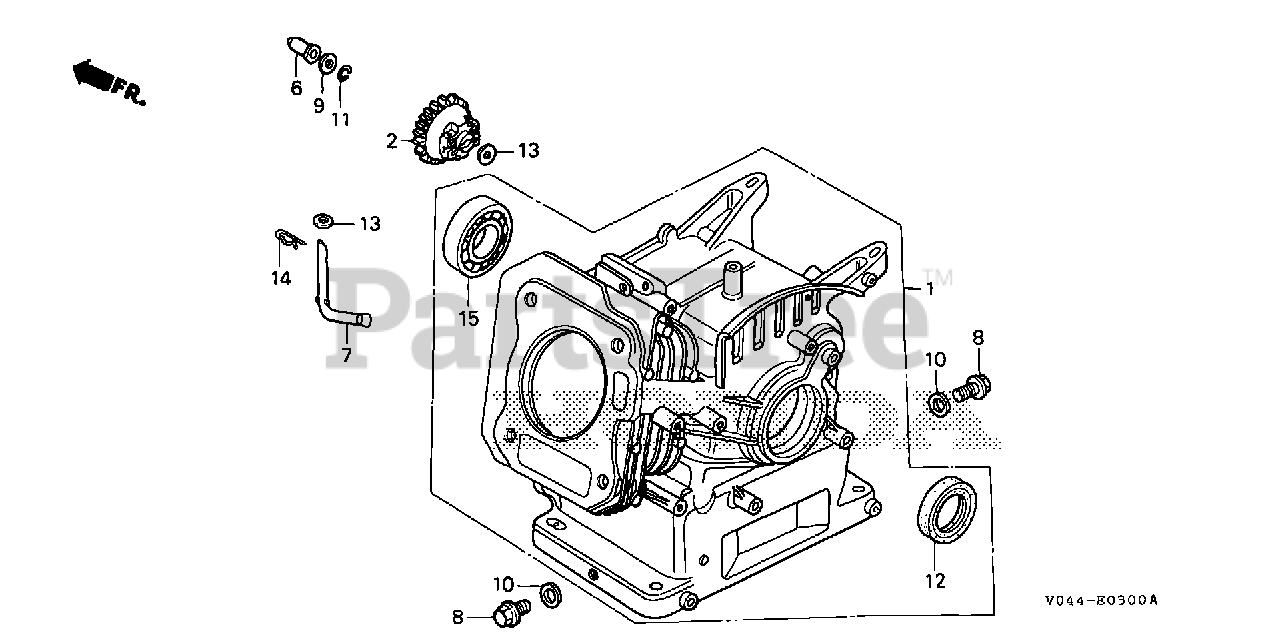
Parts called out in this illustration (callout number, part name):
1	CYLINDER ASSY.
2	GOVERNOR ASSY.
6	SLIDER, GOVERNOR
7	SHAFT, GOVERNOR ARM
8	BOLT, DRAIN PLUG
9	WASHER, THRUST (6MM)
10	WASHER, DRAIN PLUG (10.2MM)
11	CLIP, GOVERNOR HOLDER
12	OIL SEAL (25X41X6) (NOK)
13	WASHER, PLAIN (6MM)
14	PIN, LOCK (8MM)
15	BEARING, RADIAL BALL (6205TMB) (NTN)
